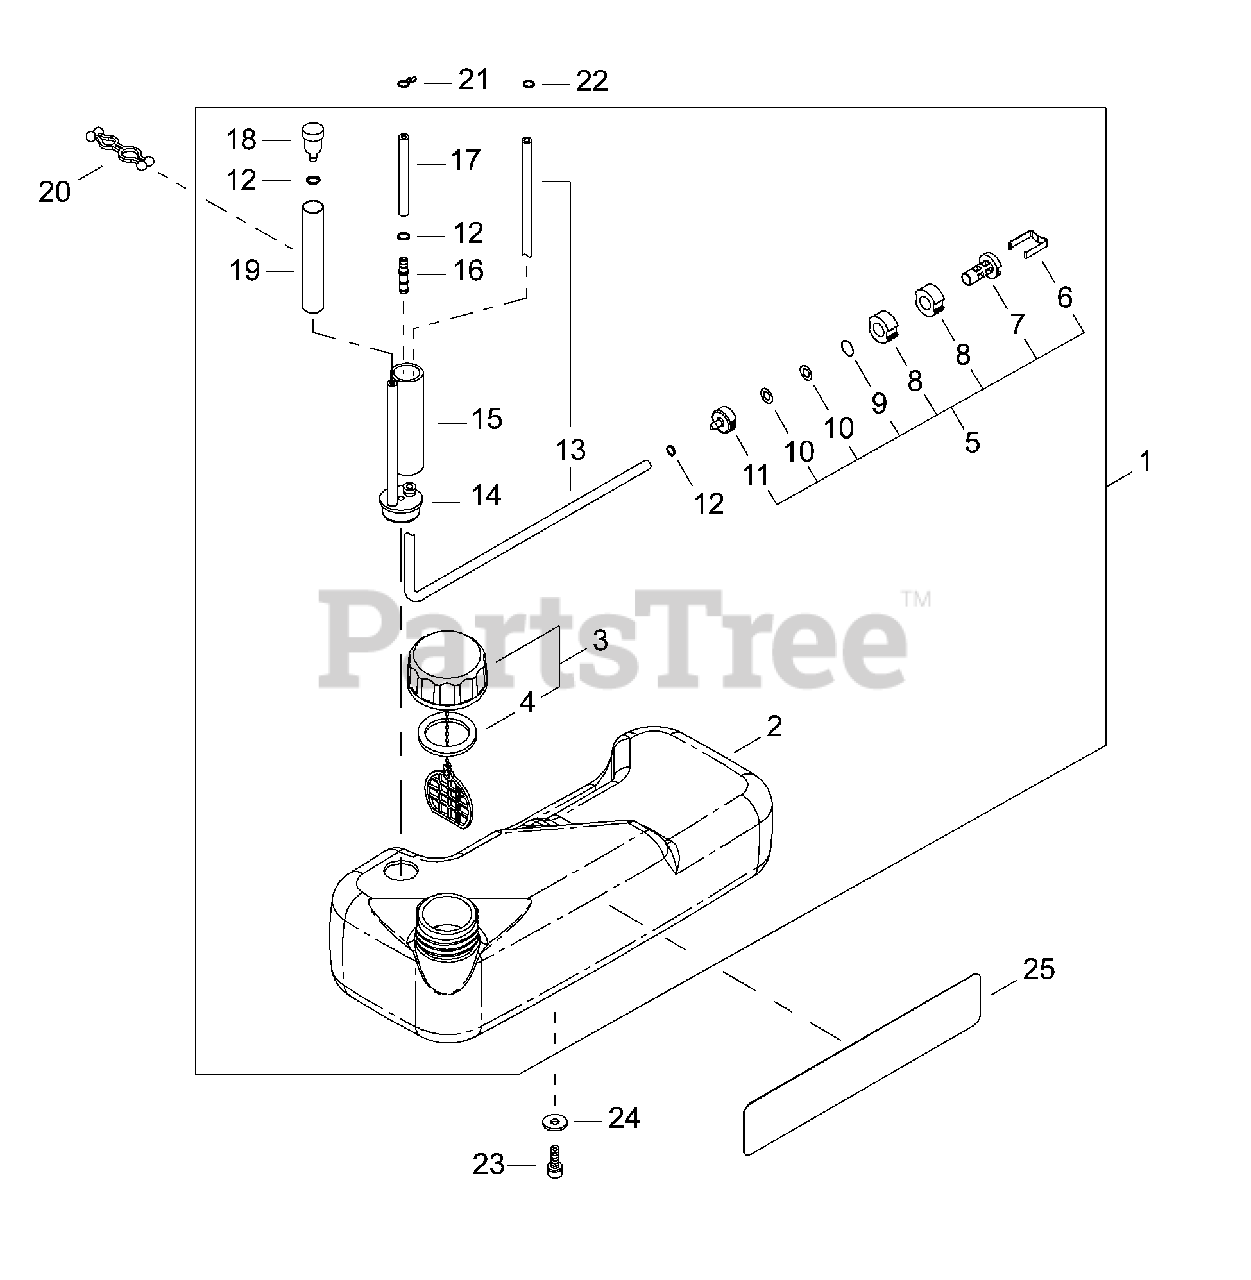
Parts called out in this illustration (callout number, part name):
1	FUEL TANK ASSY
2	TANK, FUEL
3	CAP ASSY
4	GASKET, CAP
5	FILTER, FUEL
6	CLIP, FILTER
7	CASE, FILTER
8	FILTER, FUEL
9	RING, RETAINING
10	SCREEN, FILTER
11	WEIGHT, FUEL FILTER
12	RING, RETAINING - 6
13	PIPE - FUEL
14	PIPE ASSY
15	SLEEVE
16	CONNECTOR, PIPE
17	PIPE - RETURN
18	VENT, FUEL TANK
19	TUBE
20	CLIP
21	CLIP - SPRING
22	RING, RETAINING - 6
23	SCREW - 5X14
24	COLLAR
25	LABEL - SHINDAIWA PROFESSIONAL
